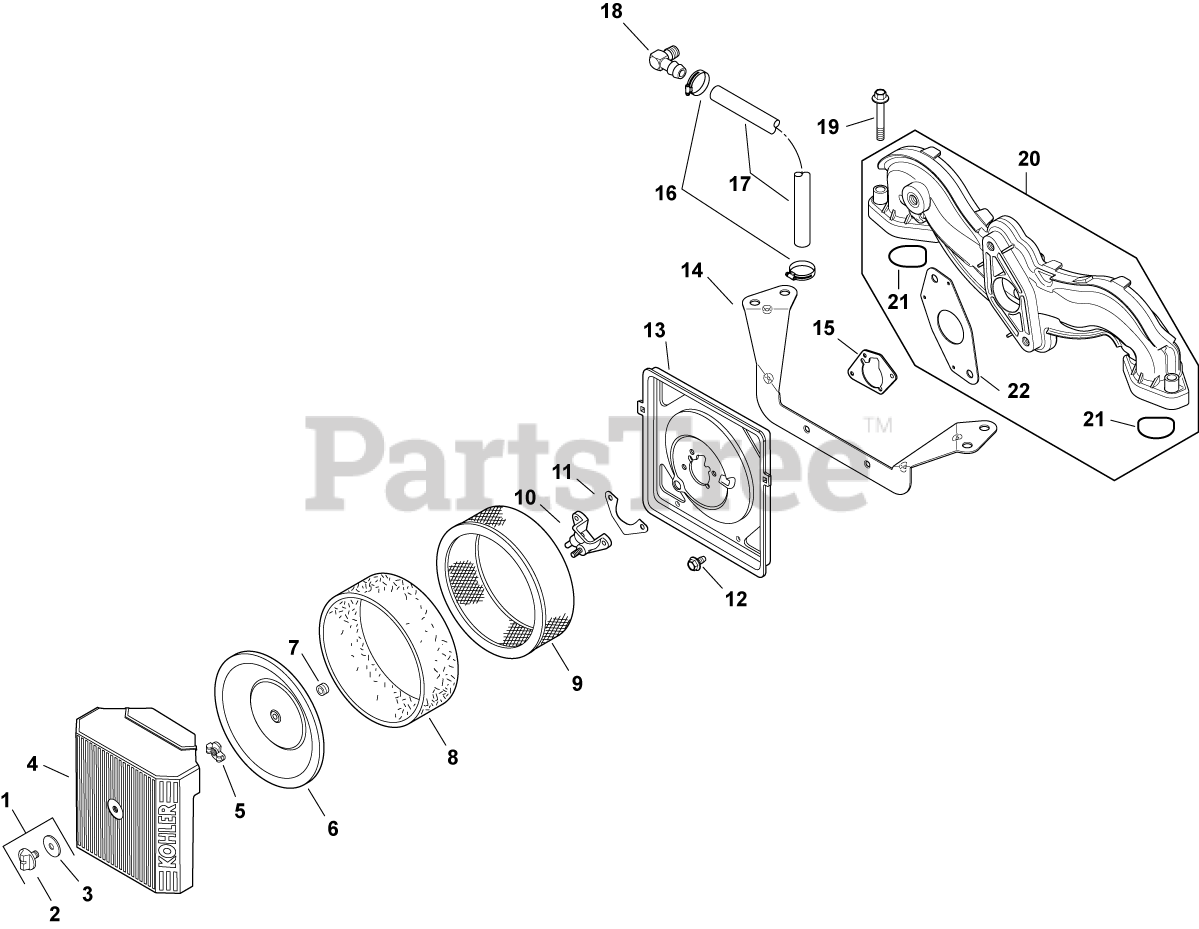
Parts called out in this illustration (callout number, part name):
1	KIT, KNOB W/SEAL
2	KNOB, COVER
4	COVER, AIR CLEANER
5	NUT, WING
6	COVER, INNER AIR CLEANER
7	SEAL, INNER AIR CLEANER
8	ELEMENT, PRECLEANER (LOW)
9	ELEMENT, AIR CLEANER - Also available Retail Packaged 47 883 03-S1 Air Filter Kit
10	CUP, SPIT-BACK W/STUD
11	GASKET, FUEL SPITBACK CUP
12	SCREW, FLG THD FRM M5X.8X10
13	BASE, AIR CLEANER-USE 24 094 87-S
14	BRACKET, AIR CLEANER BASE
15	GASKET, AIR CLEANER BASE
16	CLAMP, HOSE (KM)-USE 25 237 31-S
18	CONNECTOR, 90 DEG. HOSE
19	SCREW, FLG M6X1.0X40
20	MANIFOLD, INTAKE - PLASTIC-USE 24 164 91
21	O-RING, INTAKE PORT
22	GASKET, CARBURETOR
